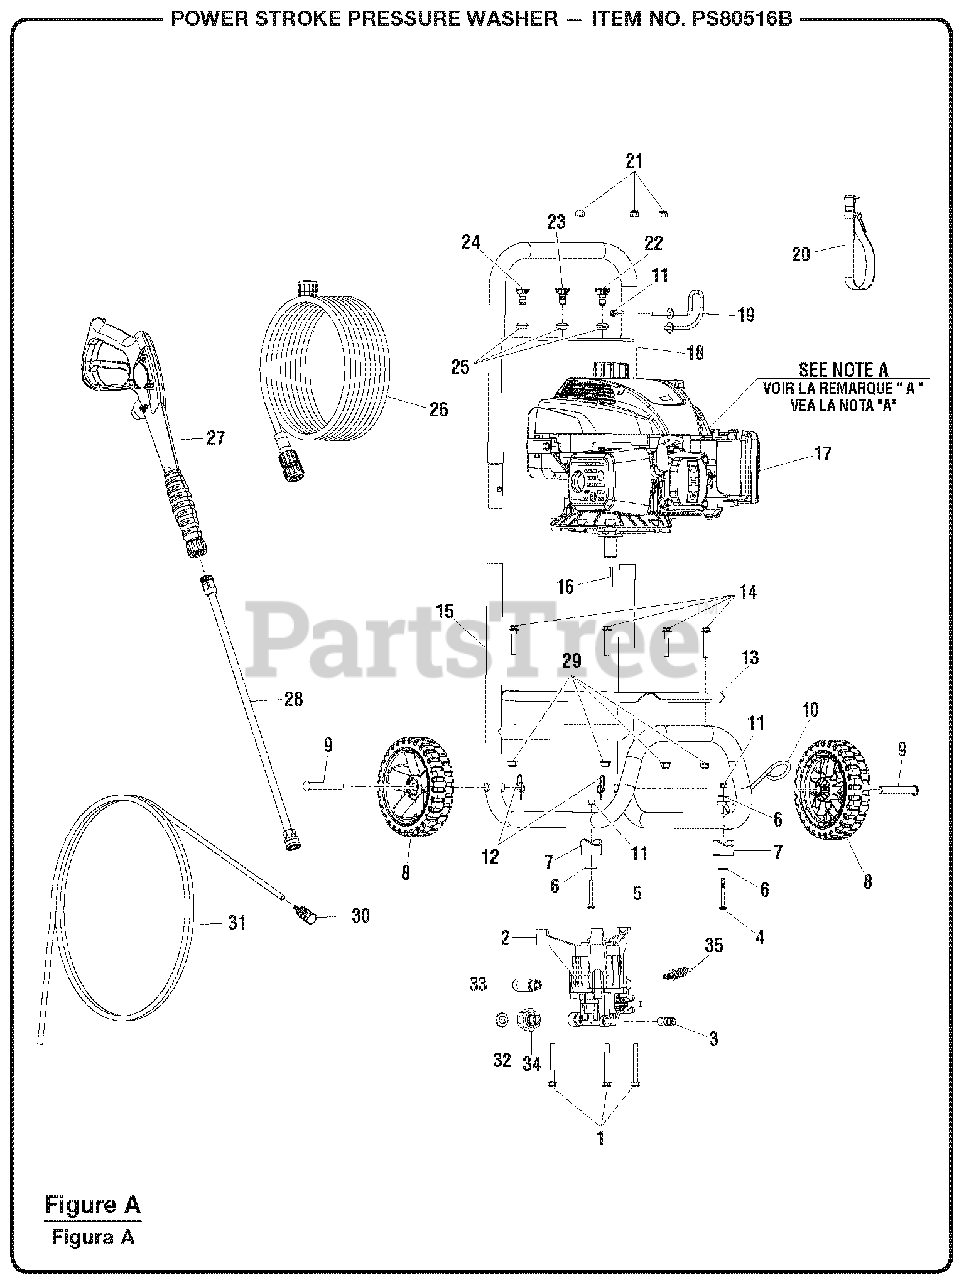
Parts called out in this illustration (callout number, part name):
1	Bolt (M8 x 70 mm, Flange Hd.)
3	Thermal Release Valve
4	Screw (1/4-20 x 2.2 in., Truss Hd.)
5	Screw (1/4-20 x 2 in., T30 Torx Hd.)
6	Washer (1/4 in.)
8	Wheel Assembly
10	Wand Holder
11	Lock Nut (1/4-20)
12	Hitch Pin
13	Engine Plate
14	Bolt (M8 x 45 mm, Flange Hd.)
15	Main Frame Assembly
16	Output Shaft Key
17	Engine (RATO, 140 cc)
18	Handle Assembly
19	Trigger Wand Holder
20	Hose Storage Strap
21	Lock Nut (M8)
22	40deg Nozzle
23	25deg Nozzle
24	Soap Nozzle
25	Nozzle Grommets
26	25 ft. Hose
27	Trigger Handle
28	Extension Wand
29	Lock Nut (M8)
30	Chemical Siphon Filter
31	Chemical Siphon Tube
32	Filter Screen
33	Outlet Tube
34	Inlet Tube
35	Unloader Valve
